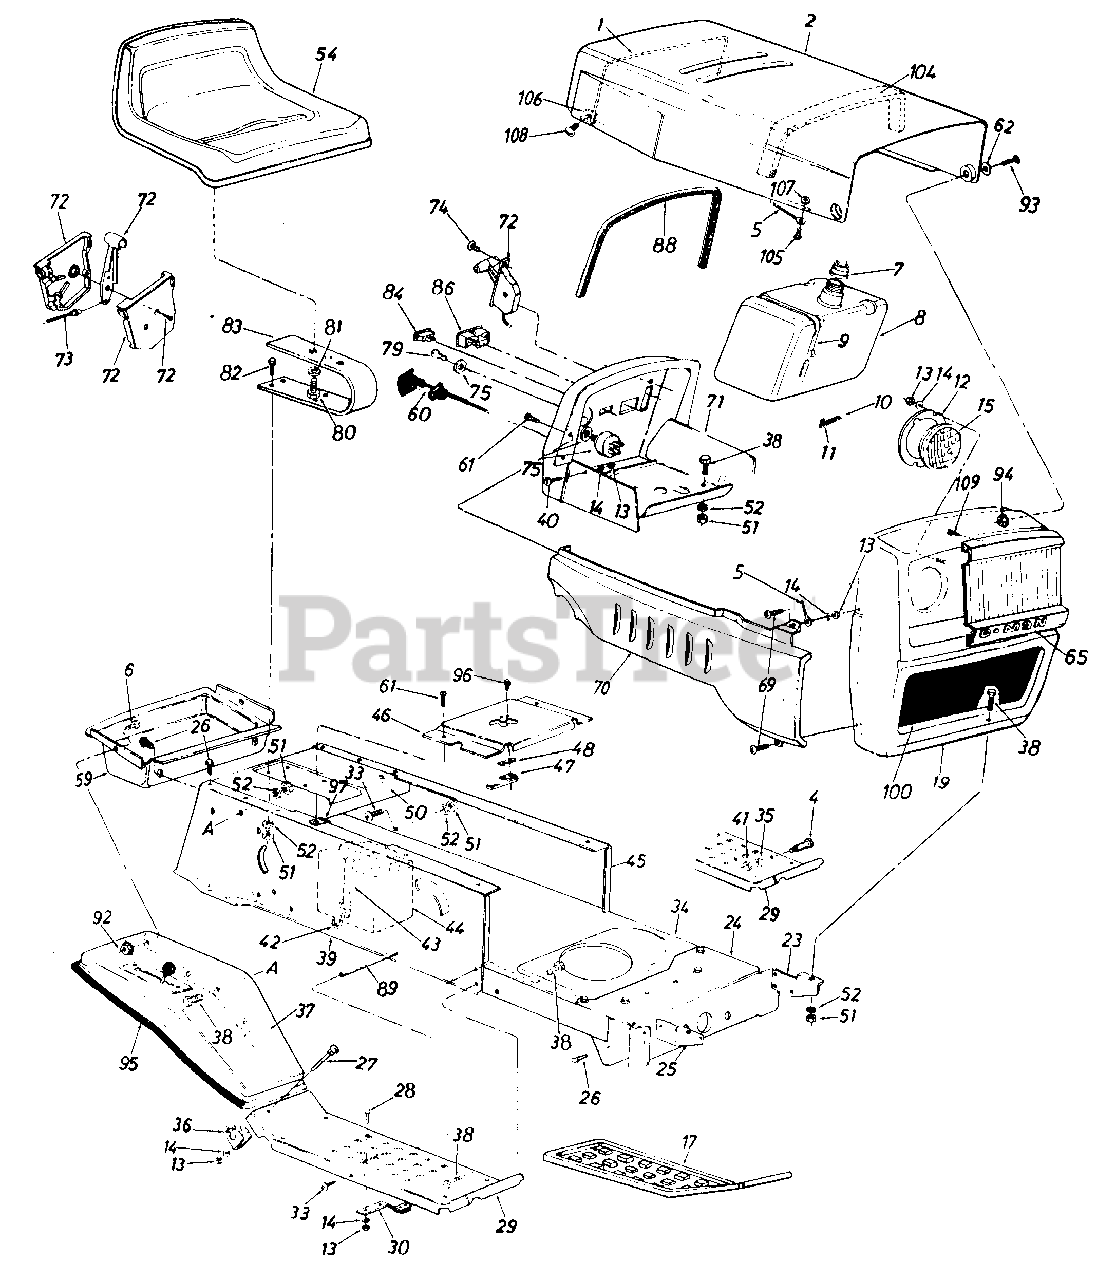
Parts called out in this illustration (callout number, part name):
1	Hood Spring
5	Hood Stop 7" Lg.
6	Truss Hd. Scr. #10-24 x 1/2"
7	Fuel Cap Gauge
8	Fuel Tank
9	Tie Strap
10	Fuel Line
11	Hose Clamp
12	Headlight Retainer
13	Hex Nut 1/4-20 Thd.
14	L-Wash. 1/4" I.D.
15	Headlight
17	Foot Pad
24	Front Pivot Brkt.
25	Grille Mount Brkt. R.H.
26	Hex Wash. Hd. AB-Tap Scr. 5/16 x .75" Lg.
27	Carriage Bolt 1/4-20 x 2.0"
28	Carriage Bolt 1/4-20 x .62"
29	Running Board
30	Blade Brake Ass'y.
33	Truss Mach. Scr. 5/16-18 x .75" Lg.
34	Lower Frame
35	L-Wash. 3/8" I.D.
36	Fender Clamp
37	Fender
39	R.H. Side Frame
40	Hex Bolt 1/4-20 x .62" Lg.
41	Hex Nut 3/8-16 Thd.
42	Battery Strap Hook
43	Battery Hold Down Strap
44	12-V Battery
45	L.H. Side Frame
46	Shift Cover
47	Reverse Safety Switch
48	Insulator Nut Plate
50	Hitch Plate
51	Hex Nut 5/16-18 Thd.
52	L-Wash. 5/16" I.D.
54	Seat Ass'y.
59	Tool Tray
60	Choke Control 29" Lg.
61	Truss Mach. Tap Scr. #10 x .50" Lg.
62	Washer .39" I.D. x .62"
65	Truss Mach. AB-Tap Scr. #10 x .5" Lg.
69	Truss Hd. Scr. 1/4-20 x .75"
70	R.H. Grille Side Panel
71	Dash Panel Ass'y.
72	Throttle Control Box Ass'y.
73	Throttle Control Wire
74	Truss Mach. AB-Tap Scr.
75	Ignition Switch
79	Ignition Key
80	Hex Bolt 1/2-13 x 1.00" Lg.
81	L-Wash. 1/2" I.D.
82	Hex Bolt 5/16-18 x 1.0
83	Seat Spring 5.5" High
84	Light Switch
86	Ammeter
88	Molding Strip 27" Lg.
89	Running Board Rod
92	Hex Sems Nut #10-24 Thd.
93	Shld. Bolt .375" Dia. x .125
94	L-Nut 1/4-28 Thd.
95	Trim Strip 57" Lg.
96	Hex Wash. Hd. AB-Tap Scr. #8 x .50" Lg.
97	Speed Nut #10Z
100	Grille Screen
104	Foam Strip
105	Pop Rivet
106	Hood Spring Retainer
107	Fl-Wash.
108	Oval Hd. Screw
109	Hex Tap Screw
